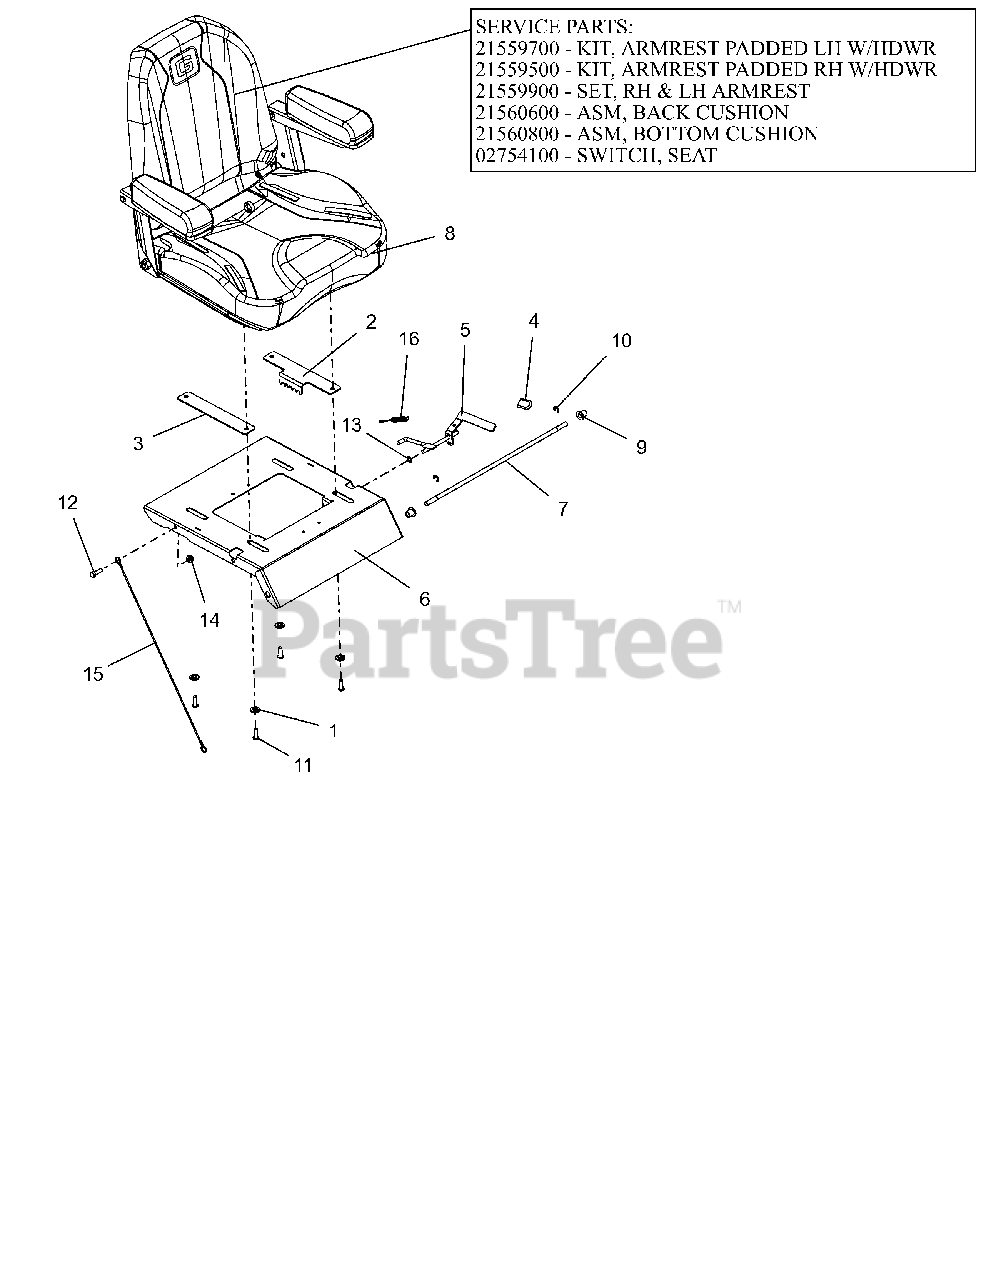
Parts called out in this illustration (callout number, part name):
1	BSHG, FLG .325X.499X.26X.88
2	PLATE, ADJUSTABLE SEAT TRACK
3	PLATE, ADJUSTABLE SEAT SLIDE
4	GRIP, SEAT LEVER, GREY
5	WLDMT, ADJUSTABLE SEAT LATCH
6	PLATE, SEAT
7	ROD, SEAT PIVOT
8	SEAT, ZTXL 2017
8	PAD, LH ARMREST
8	PAD, RH ARMREST
8	SET, RH & LH ARMREST ASM
8	ASM, BACK CUSHION-GRAVELY XL
8	ASM,BOTTOM CUSHION-GRAVELY XL
8	SWITCH- SNAP MTG N.O.
9	BSHG-FLG .38X.580X.667X.750
10	RG-RTNG-EXT .375X.035 TYP E
11	BLT,SHCS-BTN .31-18X1.00 ZCC
12	BLT,HEX .31-18X1.00 G5 ZCC
13	NUT-PUSH .312
14	NUT,NYL-FLG .31-18 GF ZCC
15	LANYARD, SEAT CABLE .093X19.5
16	SG-TENS .043X.44X3.31 WLD 5.8
